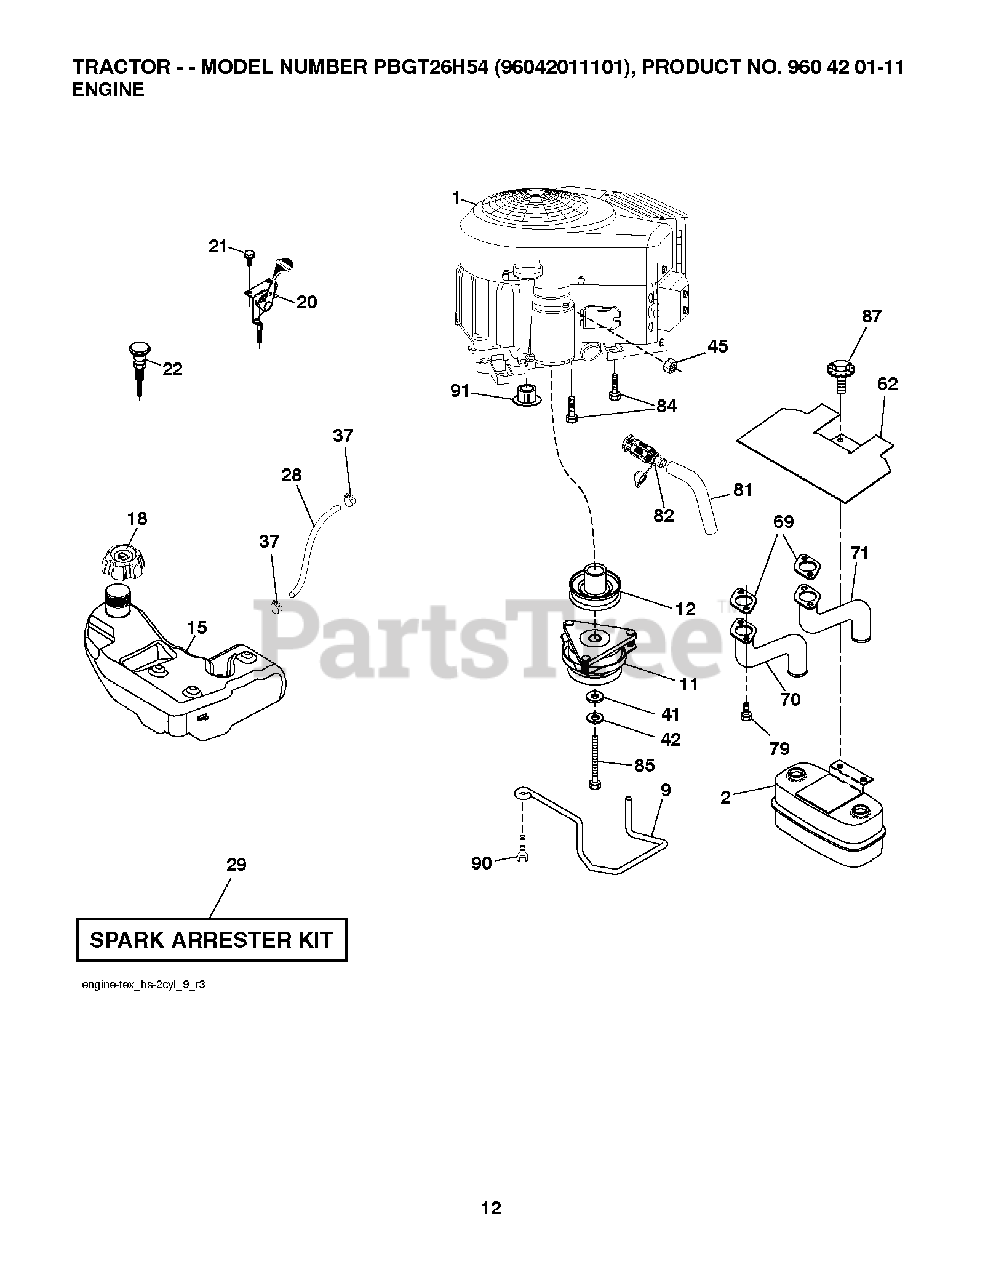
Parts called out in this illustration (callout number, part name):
1	Poulan TBD
2	MUFFLER.TWIN.CYL.LOW.TONE
9	KEEPER.BELT.ENGINE.4.2
11	CLUTCH ELECTRIC
12	PULLEY ENGINE
15	TANK.ASM.4.GAL.EPA.ONE.PORT
18	CAP ASM.FL.RTCHT.3"GRY.E10
21	SCREW.#10 X 0.750.BOS (2 2)
22	CONTROL CHOKE
28	LINE.FUEL.64"REAR.EMIS
29	KIT.SPARK ARRESTOR(392390 B&S)
37	HOSE CLAMP
42	LOCKWASHER
45	NUT
62	SHIELD.HEAT.MUFFLER
69	GASKET.MUFFLER
70	RP.EXHAUST.TUBE.LH.BS/TWIN
71	RP.EXHAUST.TUBE.RH.BS/TWIN
79	SCREW.SOCKET.HEAD.5/16-18
81	TUBE, DRAIN OIL ASM.
82	VALUE.OIL.DRAIN
84	SCREW.3/8-16
85	BOLT HEX 7/16-20 X 3.75 GR. 5
87	BOLT.5/16-18UNCX1.W/SEMS.BLK
90	SCREW 3/8-16X1
91	BUSHING.1.375OD
